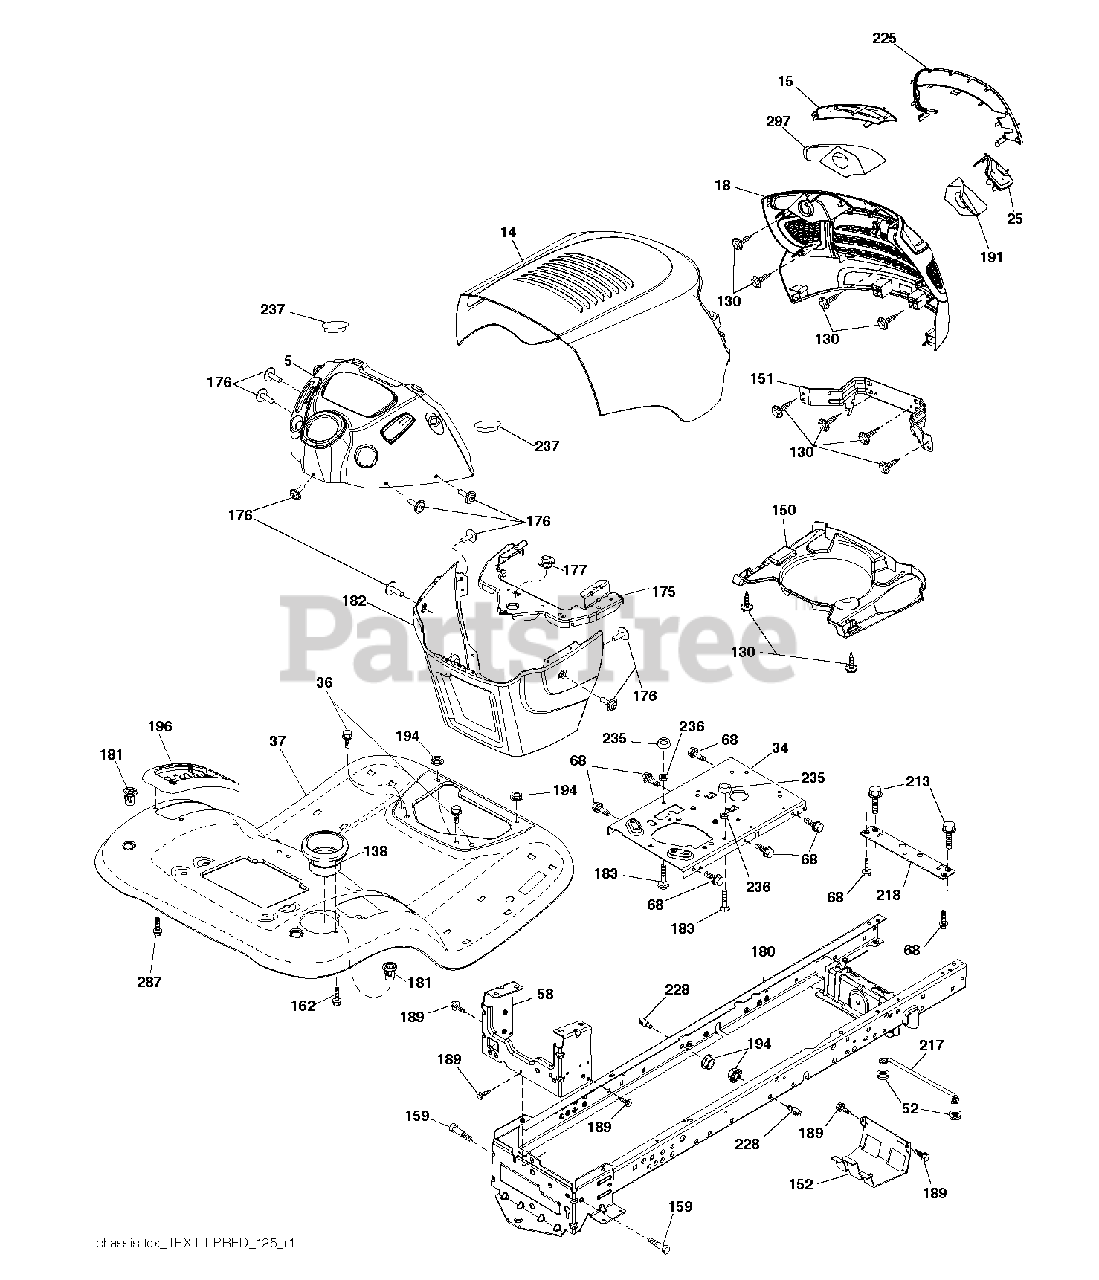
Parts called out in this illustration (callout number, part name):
5	DASH UPPER PREDATOR LT
14	HOOD.PREDATR.LT.U-FRM.TPVNT428
15	MCCULLOCH.LT.LENS.LEFT
18	GRILL.LT.GRNREIC.PPRO
25	MCCULLOCH.LT.LENS.RIGHT
34	PLATE.ENGINE.WELDED.CHASSIS
36	SCREW 5/16"
37	FENDER.TLT.W/CPH.428
52	LOCKNUT
58	DRAWBAR UPPER 2PC SMALL FENDER
68	SCR 5/16-18 X 1/2 SELFTAP ZN
130	SCREW.#10 X 0.750.BOS (2 2)
138	CUPHOLDER.TL.TEX.BLACK
150	DUCT.AIR.TOP.VENT.PREDATOR.LT
151	BRACKET.PIVOT.ALPHA.LT
152	SHIELD.BROWNING.W/TEX
159	SCREW, 3/8-16X3/4
162	SCREW.HI-LO.CONSOLE
175	CROSSMEMBER
176	SCREW.#10-24X5/8.RN.QU
177	BUSHING STEERING
180	CHASSIS
180	CHASS.WLDMNT.TL.12GA/2P.48/54
181	FEND/FTRST.PCH.CPH.NFW
182	DASH.LOWER.PREDATOR LT
183	BOLT.5/16-18X1-1/4 FULL THD
189	SCREW
191	INSERT.REFLECT.RH.MCC.LT.RT
194	NUT LOCK HEX FLANGE 5/16-18
213	BOLT
217	ROD.PIVOT.HOOD
218	X-PIECE.HOOD.STOP.NON/
225	MCCULLOCH.LT.TRIM.RING
228	STUD.FASTNER.W/ANTI-ROTATE
235	SPACER FENDER
236	NUT.CENTERLOCK.5/16-
237	PLUG.MOUNT.CARGO.BLK
287	SCREW 1/4X20
297	INSERT.REFLECT.MCC.LT.LF/RT
